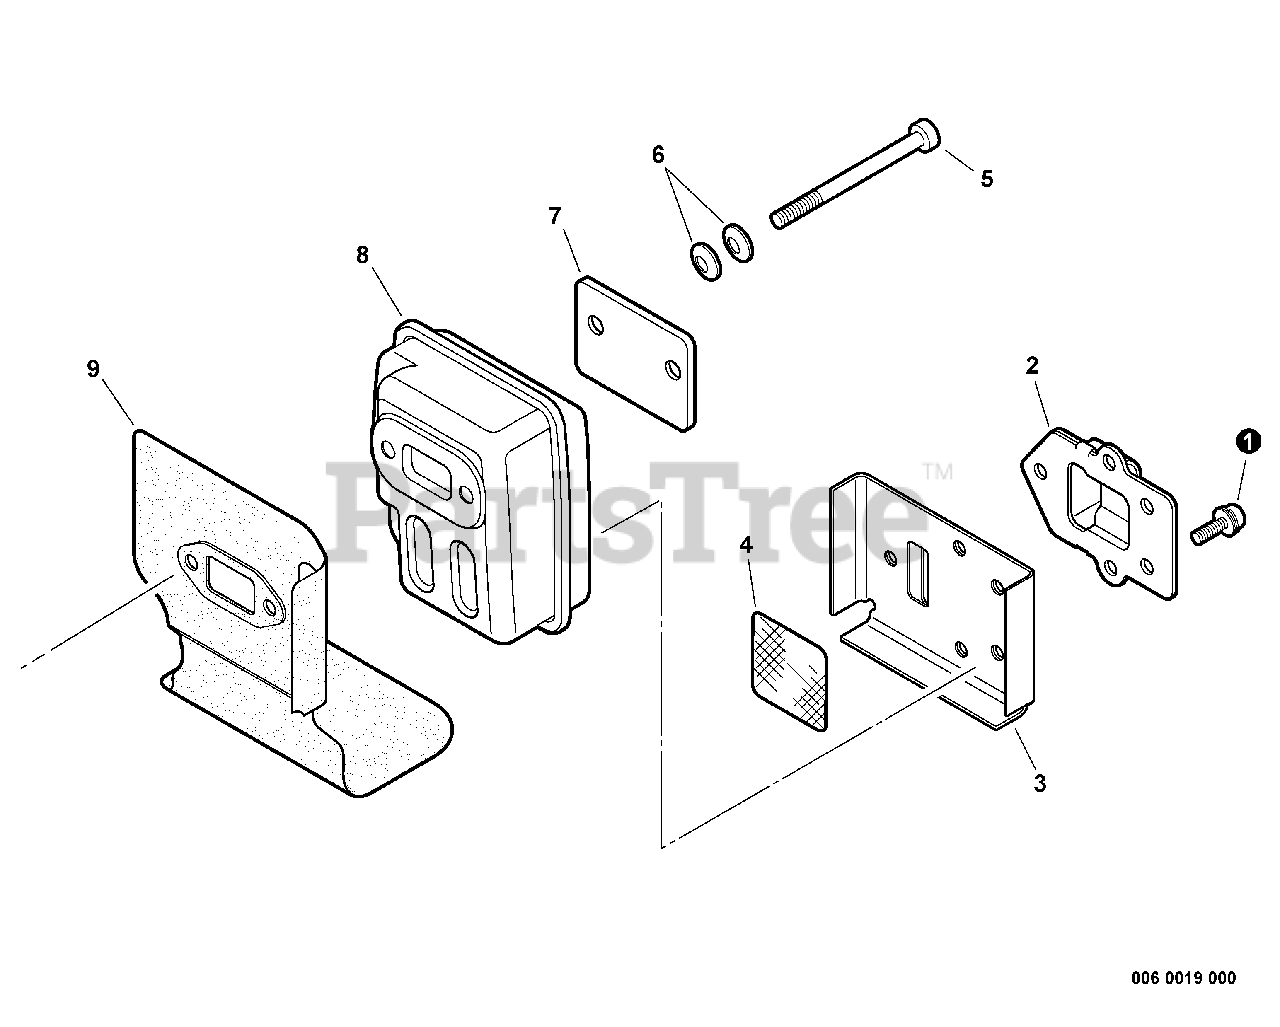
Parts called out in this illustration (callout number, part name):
1	SCREW - 4X10
2	GUIDE, EXHAUST
3	GASKET, EXHAUST
4	SCREEN, SPARK ARRESTOR
5	SCREW - 5X55
6	WASHER - CONICAL
8	MUFFLER
9	SHIELD, EXHAUST
